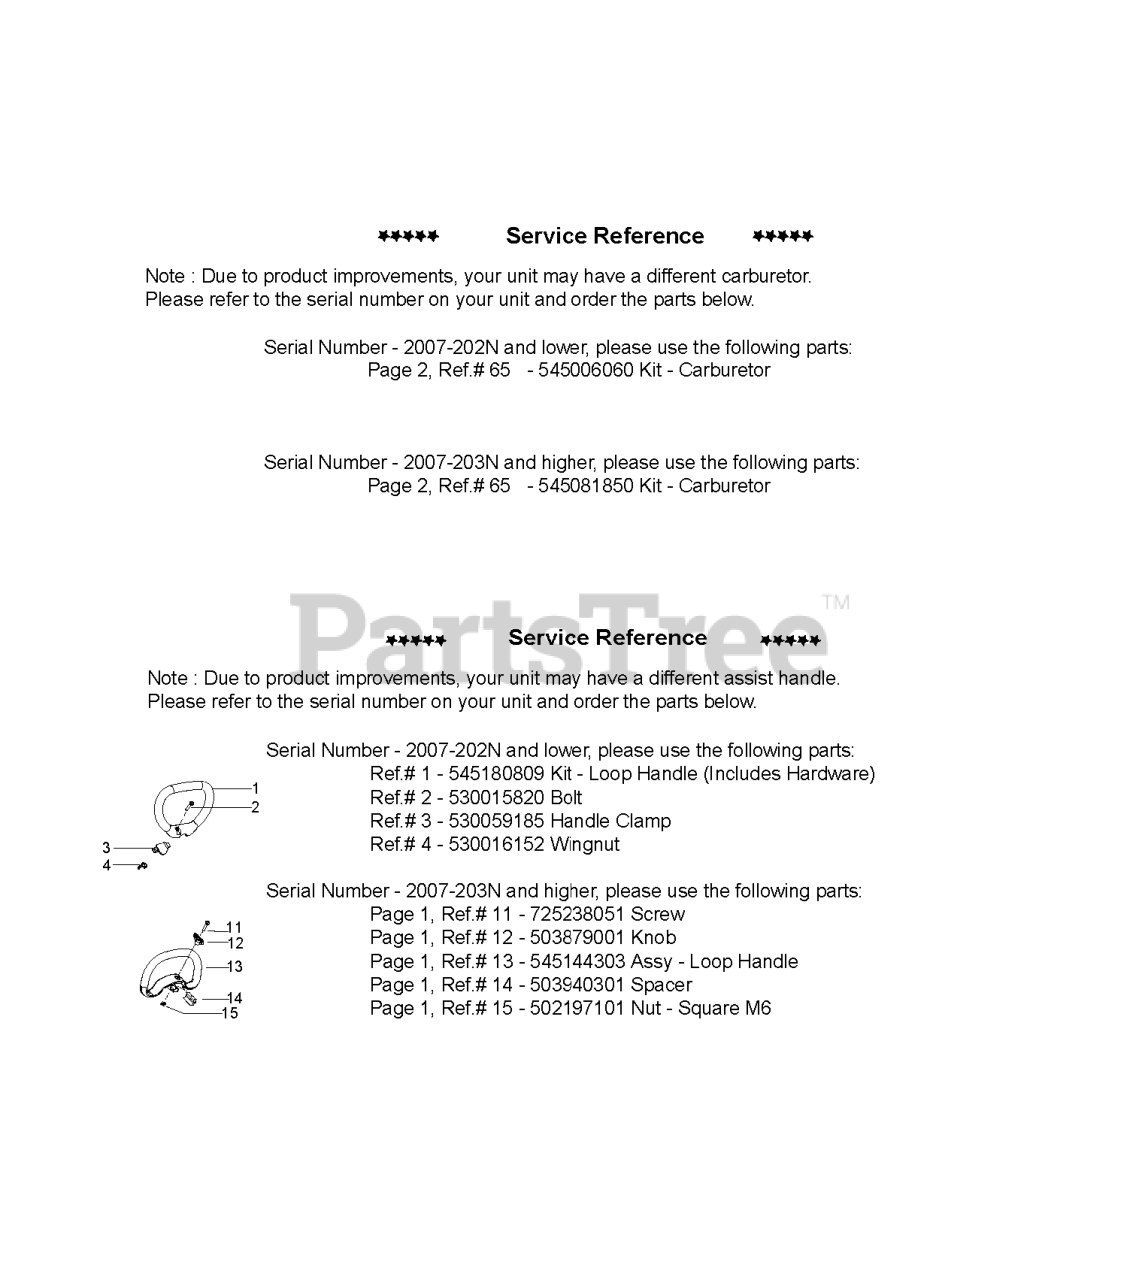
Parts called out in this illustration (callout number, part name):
1	ASSY LOOP HANDLE
2	BOLT, TYPE 2
3	CLAMP ASSIST HANDLE
4	WINGNUT, TYPE 2
11	SCREW M6X50
13	ASSY LOOP HANDLE
14	SPACER PLASTIC
65	CARBURETOR KIT W38
65	CARBURETOR
